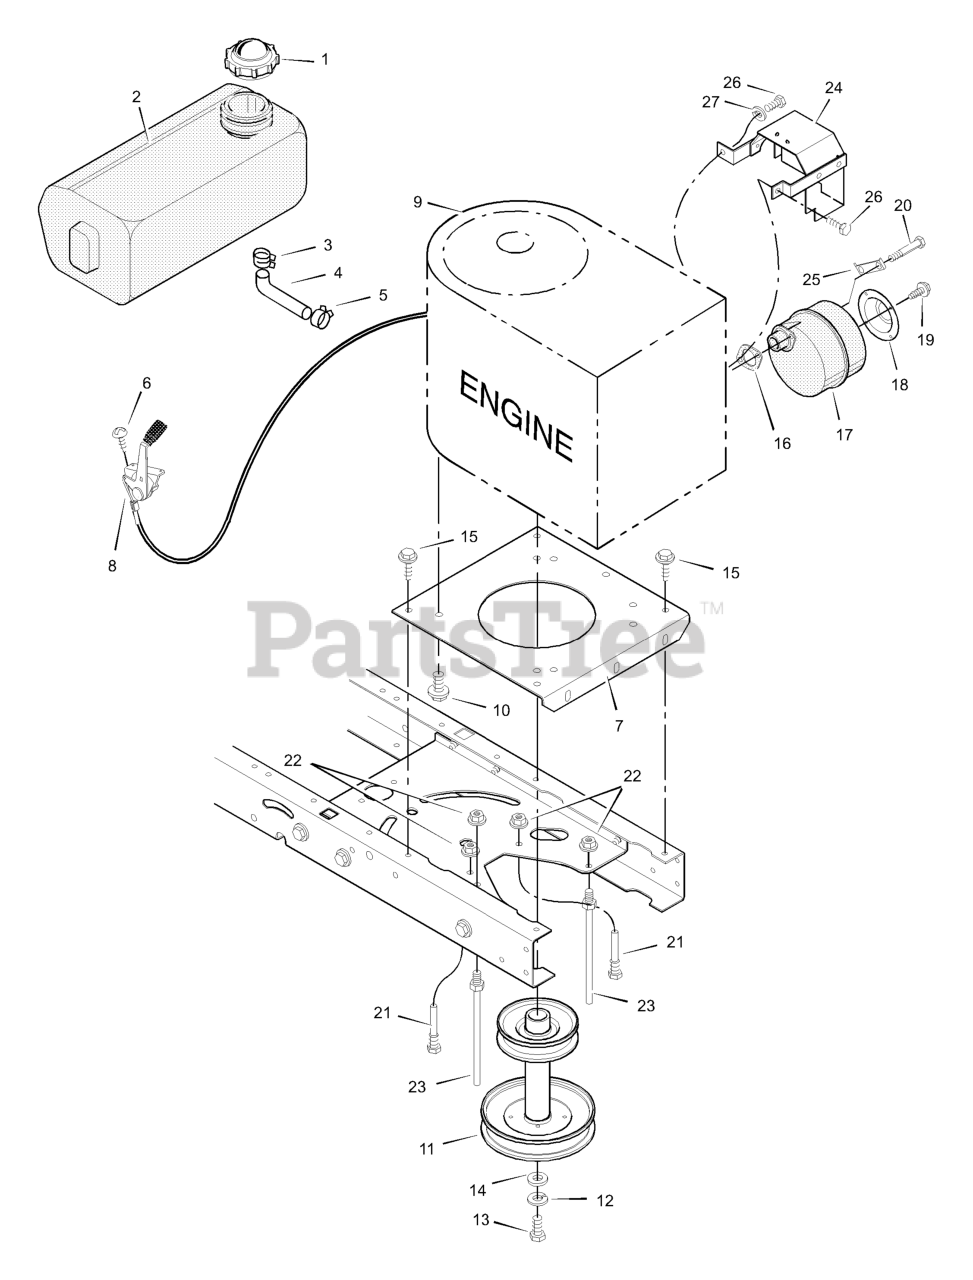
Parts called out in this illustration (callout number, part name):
1	Fuel Cap
2	Fuel Tank
3	Hose Clamp
4	Fuel Line
5	Hose Clamp
7	Plate, Engine
8	Throttle Control
9	Engine *
10	Bolt, Engine Mount
11	STACK PULLEY ASSEMBLY
12	Lockwasher
13	Bolt, Hex
16	GASKET, Exhaust
17	Muffler
18	Deflector, Muffler
20	Bolt, Hex
21	Guide, Belt
22	Nut, Flange
23	Guide, Belt
24	Shield, Heat
25	Lock, Screw
